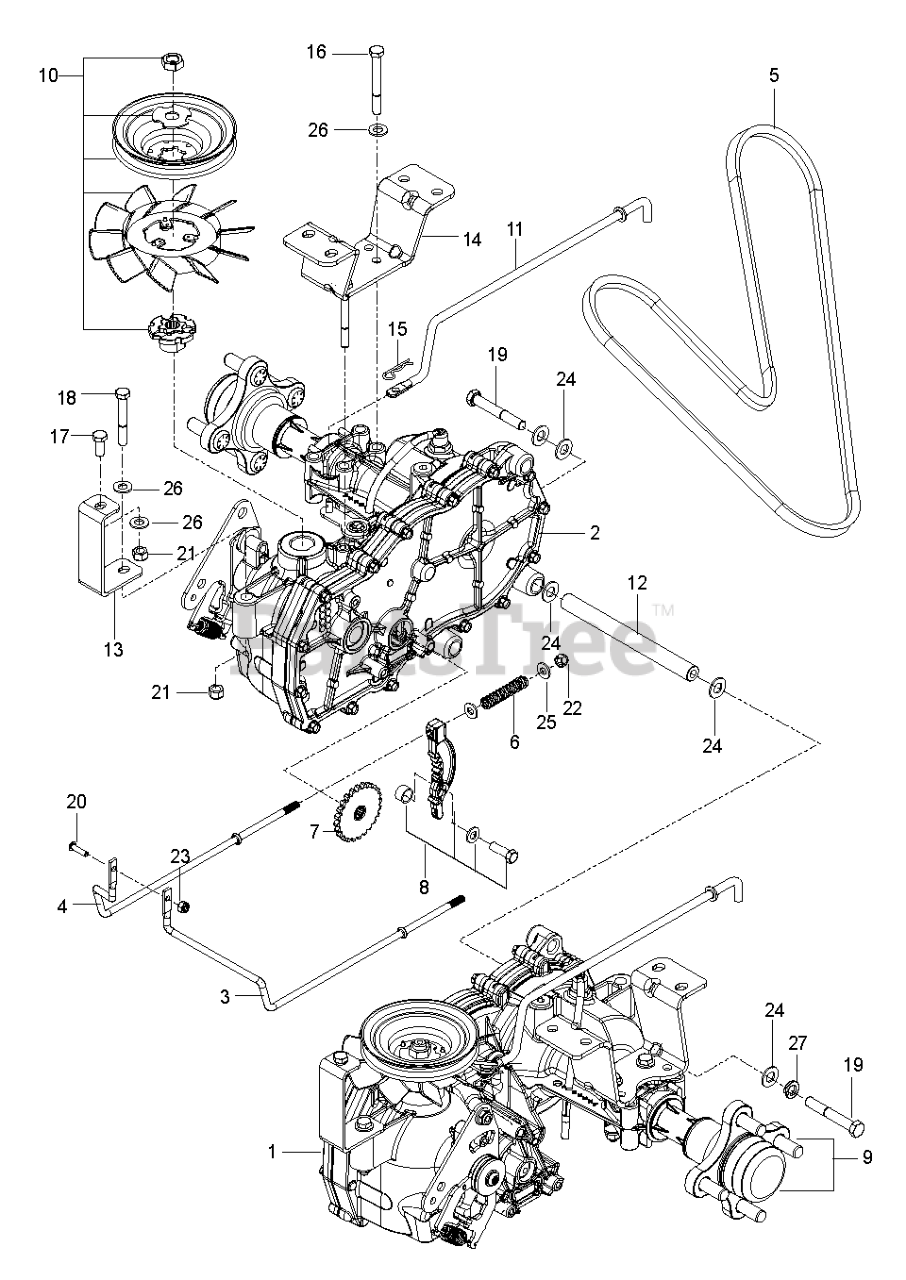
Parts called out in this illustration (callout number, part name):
1	HG_EZT, LT
2	HG_EZT, RT
3	LINKAGE.BRAKE.LT
4	LINKAGE, BRAKE RT
5	BELT, HYDRO PUMP
6	SPRING
7	HG_DISC COG BRAKE 51635
8	HG_KIT BRAKE ARM (EZT)
9	HG_KIT, HYDRO-GEAR HUB
10	KIT FAN/PULLEY 72137
11	LINKAGE, BYPASS, EZT
12	SPACER TUBE EZT
13	SUPPORT.FRONT.TRANS.PNTX431
14	BRACKET.EZT.MOUNT.REAR.PNTX431
15	HAIRPIN #2
16	BOLT HEX
17	HCS 5/16C X 3/4
18	BOLT.FIN HEX 5/16-18UNC X2 1/4
19	HCS 3/8C X 2 1/2
20	SCREW.TRSHD.SL.#10-24UNC X
21	NUT.71038.31-18.HEX.NYLOCK
22	RP_NUT 1/4-20 NYLOC
23	NUT 10-24 NYLOC
25	WASHER
26	WASHER
27	SLW 3/8 STD
